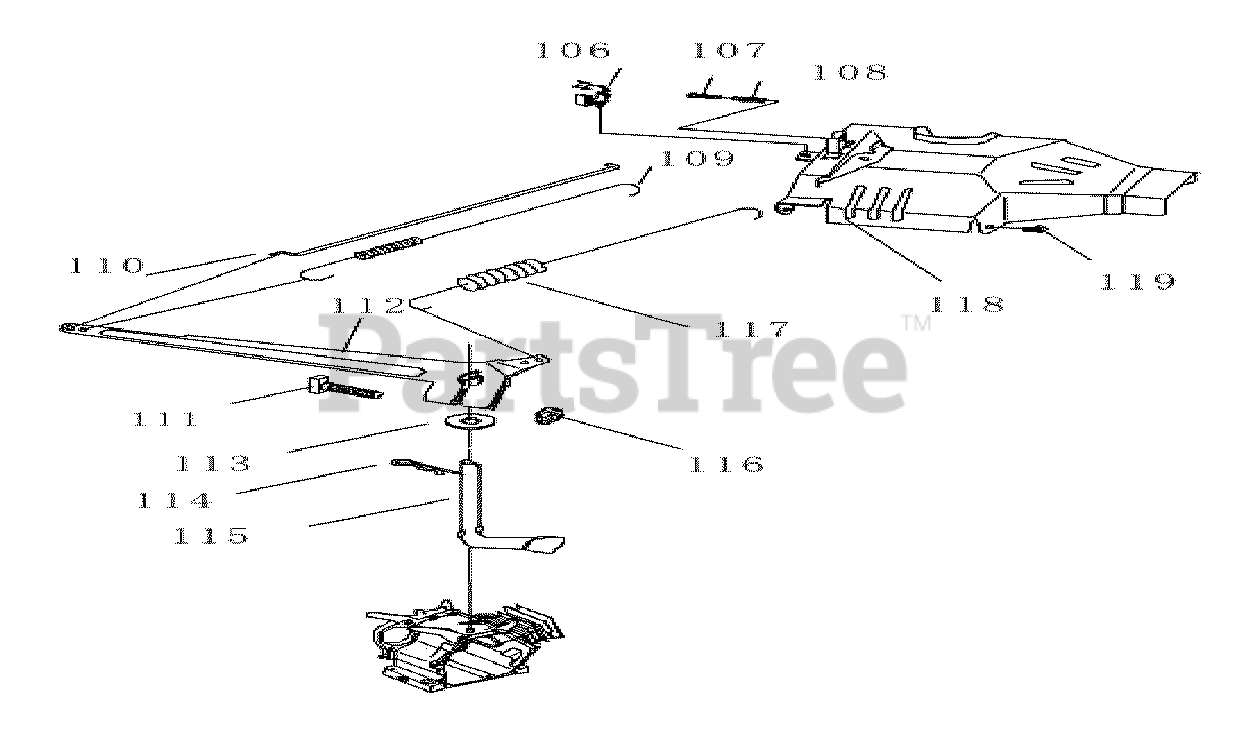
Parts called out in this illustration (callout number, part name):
107	M5 x 35 pan head screw
110	Link rod
111	M6 square head bolt
112	Governor arm
113	Plain washer
115	Governor shaft
116	M6 flanged nut
118	Wind guide
119	M6 x 12 flanged bolt
